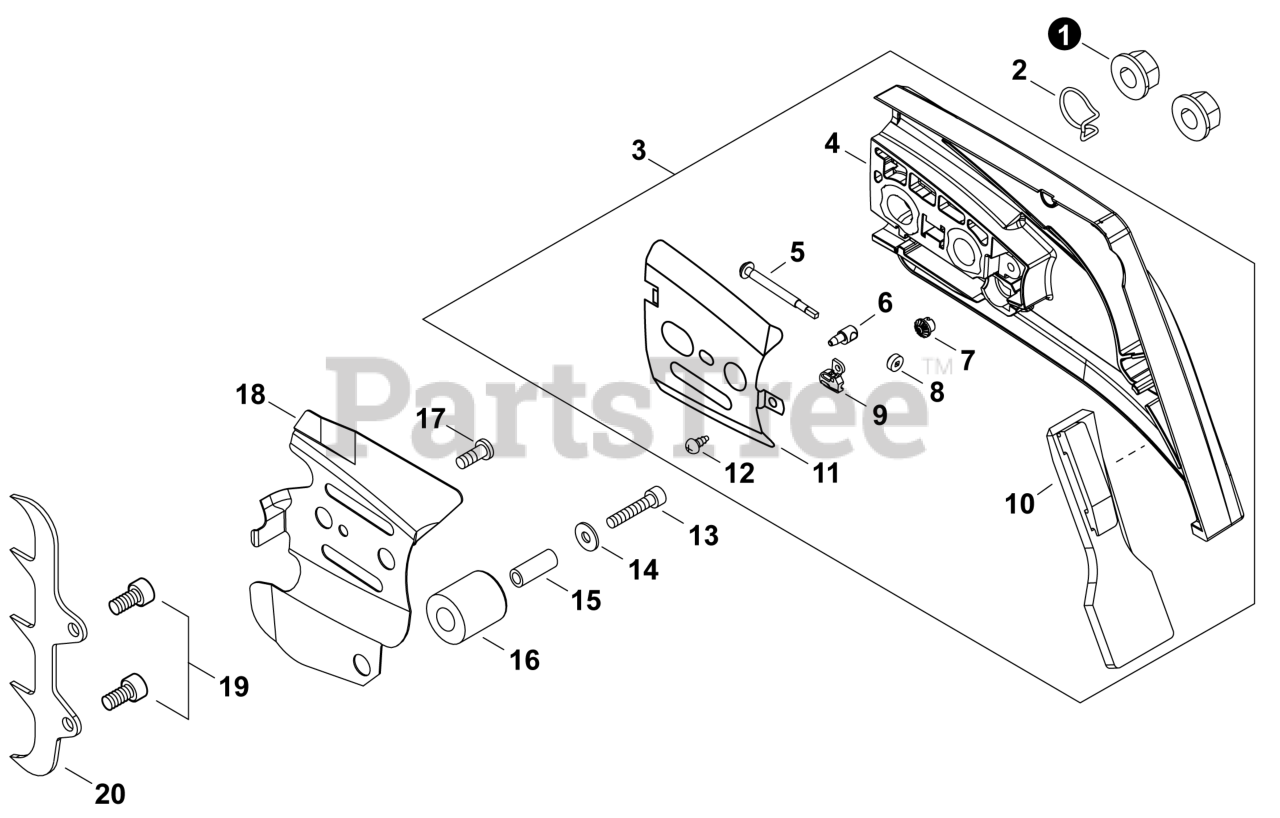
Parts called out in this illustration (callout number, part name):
3	COVER ASSY, CLUTCH
4	GUARD, SPROCKET
5	SCREW, CHAIN TENSION
6	TENSIONER, CHAIN
7	GEAR, BEVEL
8	GEAR, BEVEL
9	COLLAR 8
10	PROTECTOR
11	PLATE, GUIDE - OUTER
12	SCREW 4×8
13	BOLT 5×30
14	WASHER, FLAT 5.5×10×0.8
15	COLLAR 5
16	CHAIN CATCHER
17	SCREW M4×7
18	PLATE, GUIDE - INNER
19	BOLT 5×12
20	SPIKE, BUMPER
